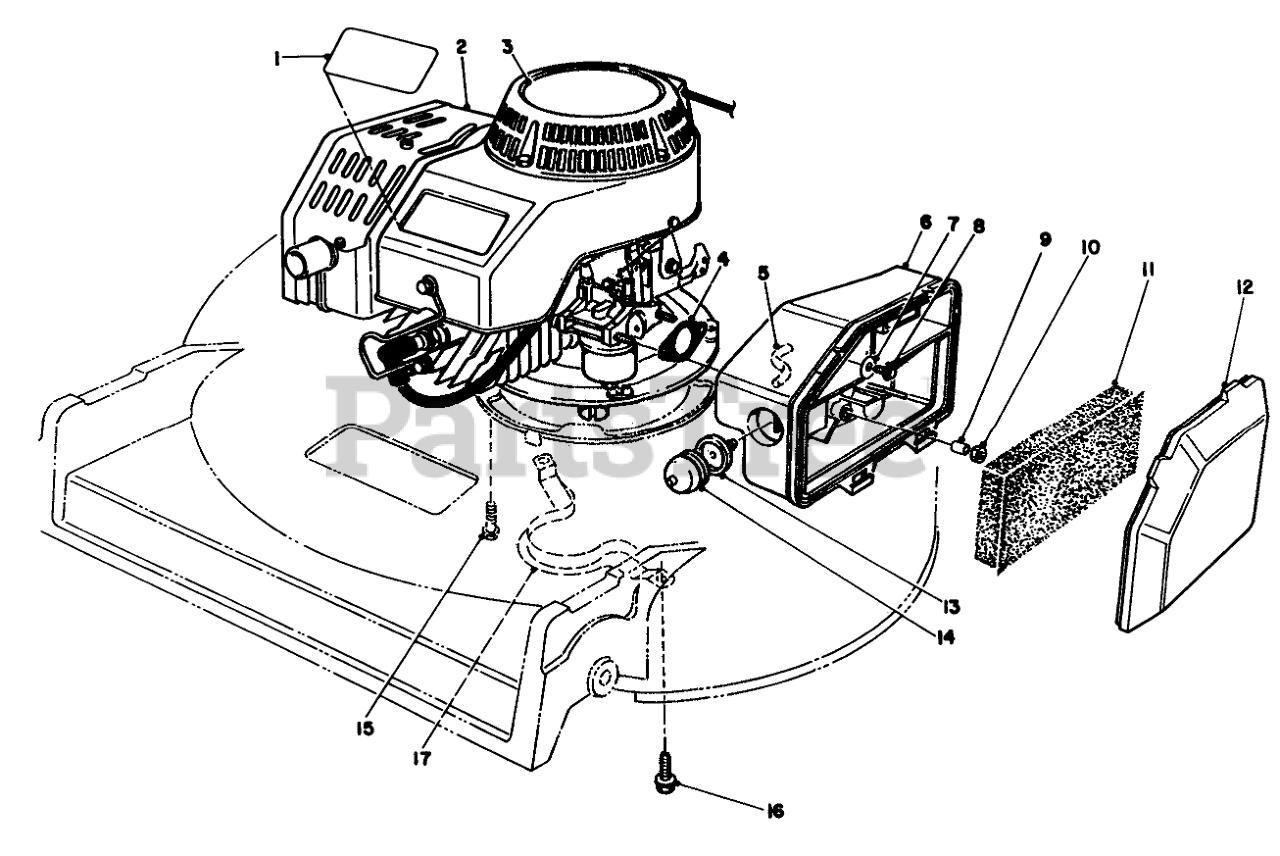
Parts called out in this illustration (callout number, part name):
1	DECAL - PROLINE
2	ENGINE ASM
3	DECAL-2 CYC RECOIL COMM
4	GASKET-AIR CLEANER
5	HOSE-PRIMER
6	BODY-AIR CLEANER
7	WASHER-FLAT
8	SCREW-HH
9	SPACER
11	ELEMENT-AIR CLEANER
12	COVER-AIR CLEANER
13	BODY-PRIMER
14	BULB-PRIMER
15	PULLEY-DRIVER
16	KEY-SQUARE
17	SPACER-BLADE RETAINER
18	WASHER-LOCK, INTERNAL
19	SCREW-HWHTF
20	Blade
21	SCREW-BLADE
22	WASHER-LOCK
23	RETAINER-BLADE
24	PROTECTOR-CRANKSHAFT
25	SCREW-HHF
26	Accelerator
27	EXTENSION-MUFFLER GUARD
29	Staple
